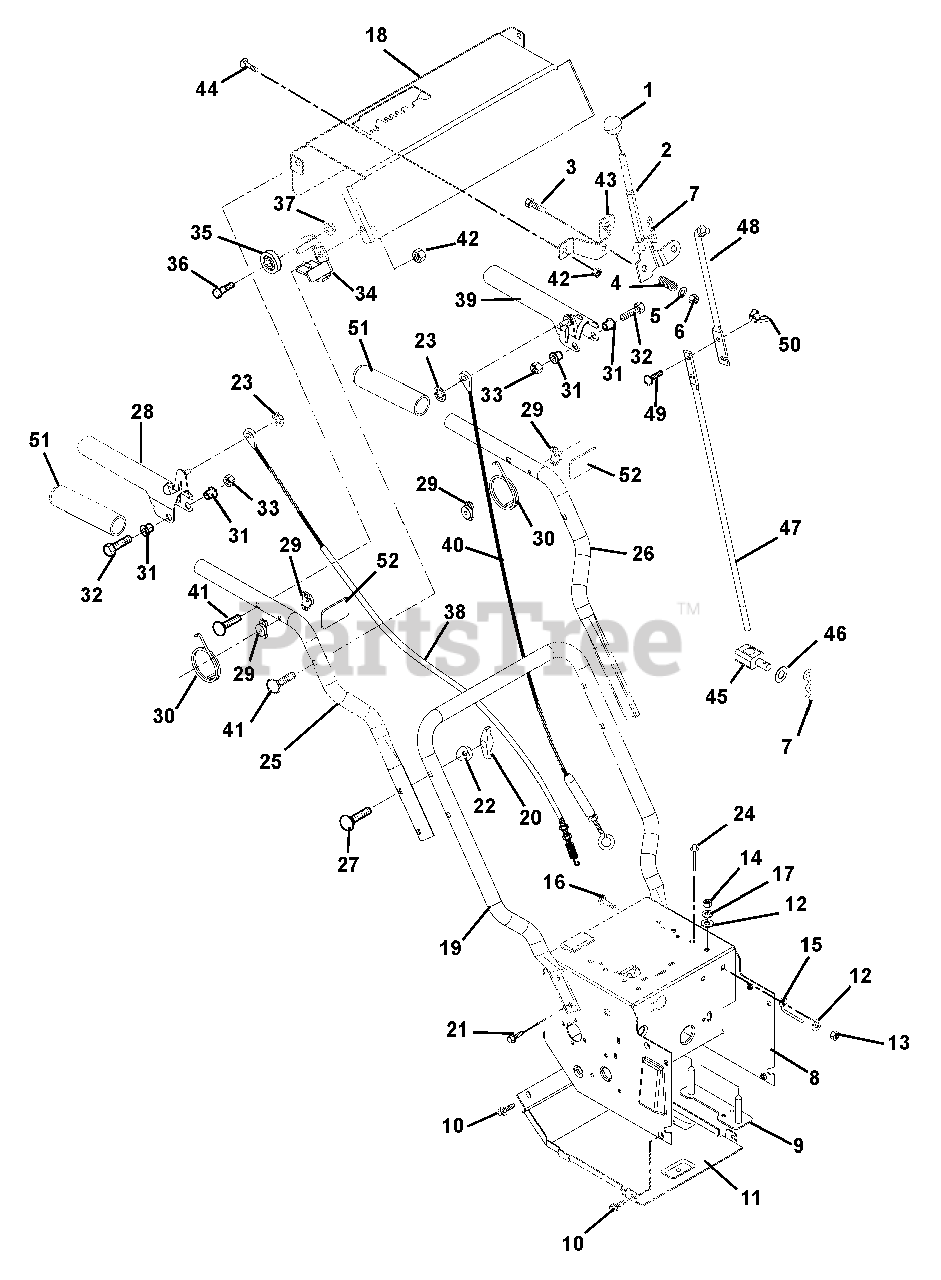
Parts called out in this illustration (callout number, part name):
1	KNOB,BALL -BLACK 1.47" .375-16
2	WMT, SHIFT LEVER
3	@BLT-HEX .38-16X2.00 GR5 YWZC
4	SG-COMP .125X.781X1.250
5	@WSHR-FL-STL.438X1.00X.083 YWZ
6	@NUT-LK-CTR .38-16 YWZC
7	PIN-HAIR INT .08X.18X1.18 YWZC
8	WELDMENT, FRAME - COMPACT SNOW
9	STRAP, ENGINE BOLT-WELDMENT
10	@SCR-TAP .25-20X.37 HWH YWZ TR
11	COVER BOTTOM
12	@WSHR-FL-STL.38X.875X.083 YWZC
13	@NUT-LK-CTR .31-18 YWZC
14	@NUT-HEX .31-18 YWZC
15	BELT FINGER LOWER
16	@BLT-RHDSSQNK .31-18X.75 G5YZ
17	WSHR-LK .312X.097 HVY YWZC
18	CONTROL PANEL W/DECAL
19	HANDLEBAR, LOWER - COMPACT
20	KNOB - WING .312-18 UNC
21	BLT-SERHFWH .38-16X.75 YWZC
22	SPACER, HANDLEBAR
23	RG-RTNG-EXT .250X.010
24	RVT-POP .187X.45 DOME SS FBF64
25	HANDLEBAR, UPPER - RH COMPACT
26	HANDLEBAR, UPPER - LH COMPACT
27	@BLT-RDHDSQNK .31-18X2.25 G5YZ
28	PADDLE, CLUTCH - RH COMPACT
29	SPACER, HANDLEBAR
30	SPRING, TORSION
31	BSHG, FLG .266X.42X.150 PM
32	@BLT-HEX .25-20X2.25 GR5 YWZC
33	NUT-JAM-NYL .250-20 W/INSERTYZ
34	BRACKET, CABLE MOUNT
35	PULLEY, CABLE
36	BOLT, SHLDR-.375X.375X.25-20
37	@NUT-LK-CTR .25-20 YWZC
38	CABLE, AUGER
39	PADDLE, CLUTCH - LH COMPACT
40	CABLE, TRACTION
41	BLT-RDHDXLSQNK .31-18X1.5 G5YZ
42	@NUT-LK-TOP-FLG .31-18 YWZC
43	BRACKET, SHIFT MOUNT
44	@BLT-RHDSSQNK .31-18X.62 G5YZ
45	PIVOT,SHIFT ROD .375-16(TRUNN)
46	@WSHR-FL-STL.281X.62X.065 YWZC
47	ROD, SHIFT - LOWER
48	ROD, SHIFT - UPPER
49	@BLT-RDHDSQNK .25-20X.75 G5YZ
50	NUT-LK WING .250-20 YWZC
51	HANDLE GRIP
52	BUMPER PAD
